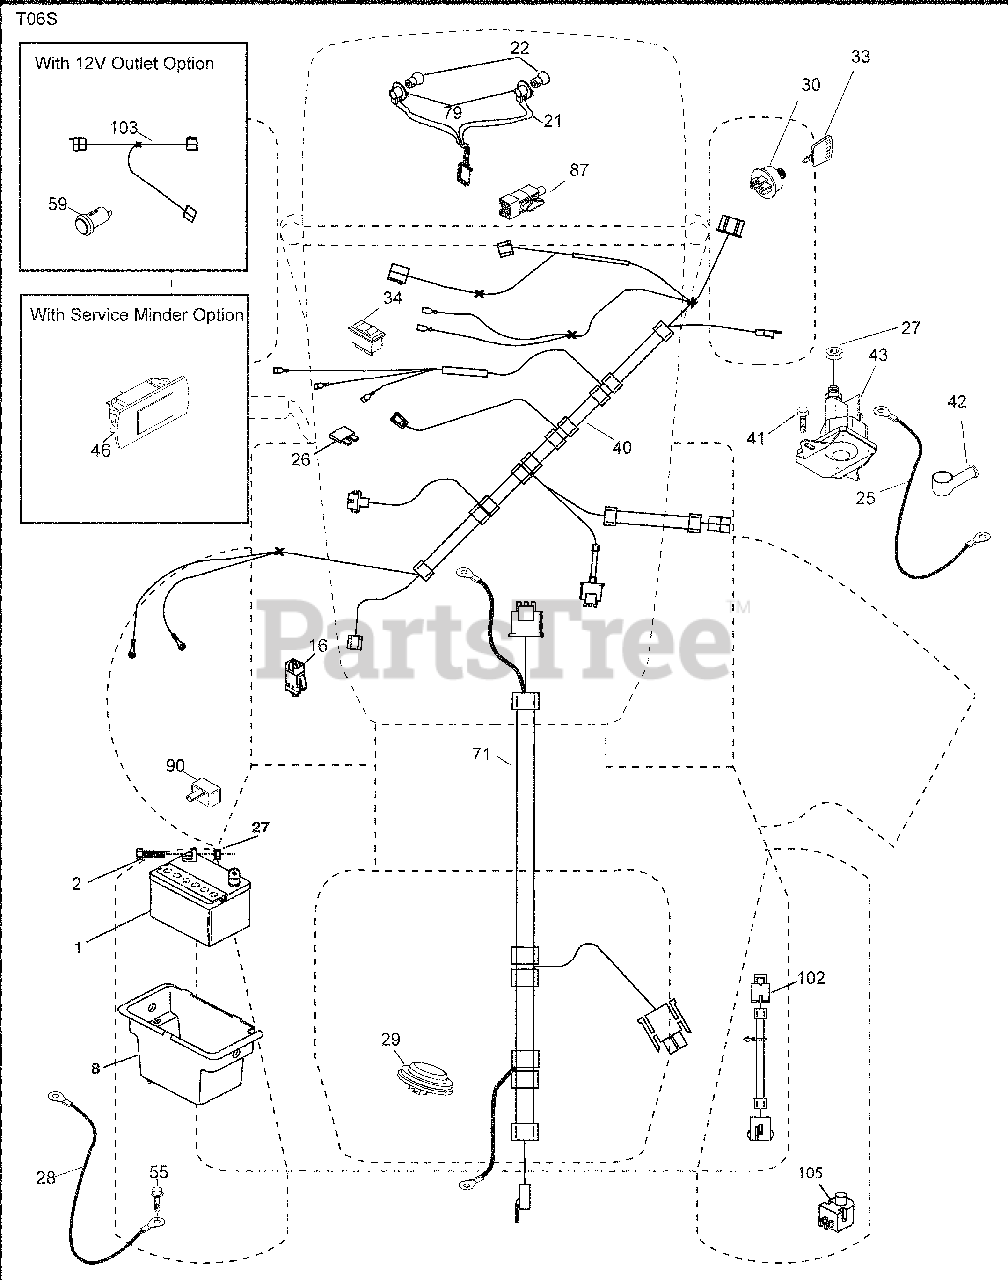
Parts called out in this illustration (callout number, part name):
1	Battery
2	Bolt Hex Head 1/4-20 x 3/4
8	Box Battery
16	Switch Interlock Push-In
21	Harness Socket Light w/4152J
22	Bulb Light
25	Cable Starter
27	Nut Keps Hex 1/4-20 unc
28	Cable, Ground
29	Switch, Seat
30	Switch, Ign
34	Switch Light/Reset
40	Harness Ign. Dash
41	Screw Thd Cut 1/4-20 x 1/2
42	Cover, Terminal
43	Solenoid
46	Gauge Serviceminder Hrmtr
55	Screw Thdrol 5/16-18 x 3/4 TYTT
71	Harness Ign.
79	Socket Asm. Bulb
87	Switch Interlock Clutch
90	Cover Terminal
102	Harness Pigtail
105	Switch Reverse TT GT
